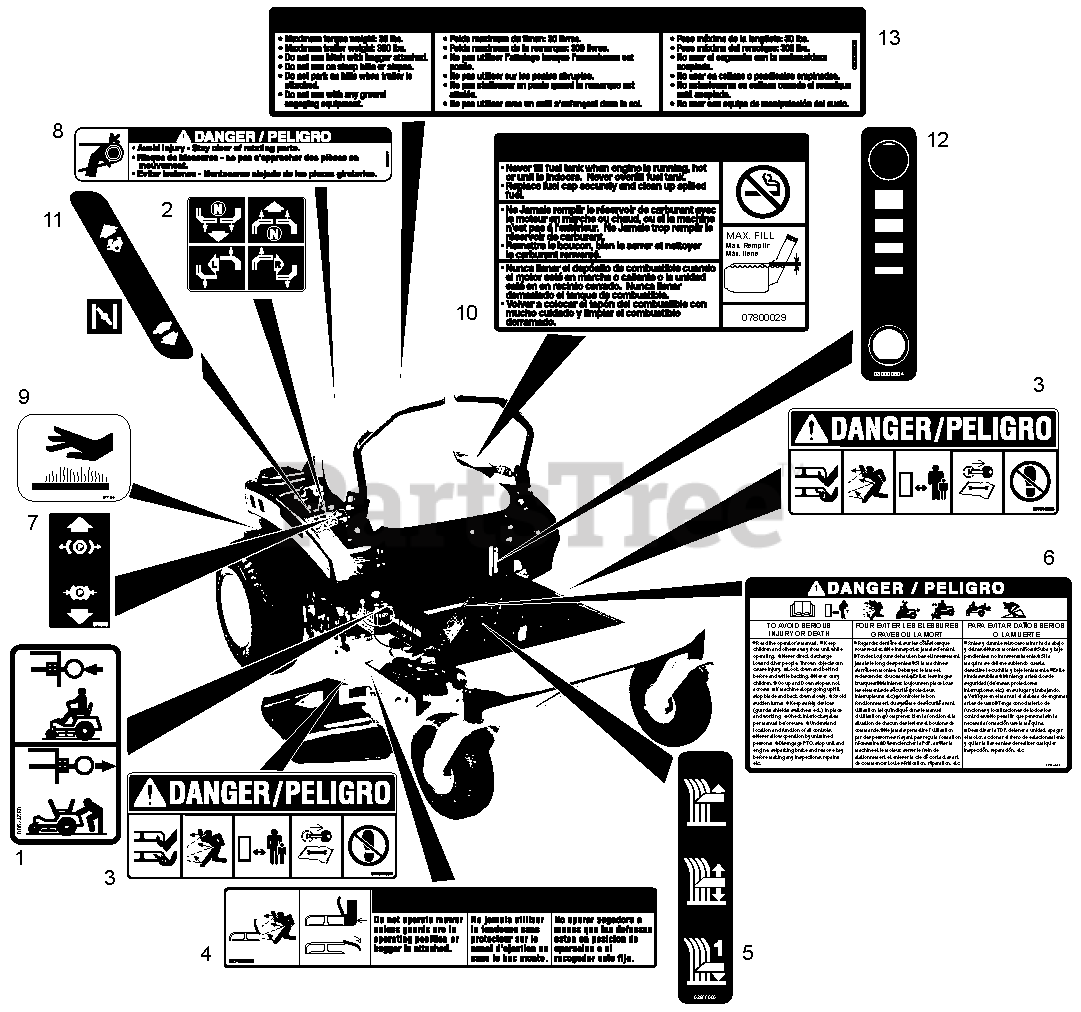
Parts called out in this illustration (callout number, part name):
1	Decal, Transmission Disconnect
2	Decal, Instructional Steering
3	Decal, Mower Pan Head Danger
4	Decal, Warning
5	Decal, Cut Height
6	Decal, Bilingual Danger
7	Decal, Parking Brake Lever
8	Decal, Danger
9	Decal, Hot Surface
10	Decal, Fuel Warning
11	Decal, Throttle Control
12	Decal, Fuel Level
13	Decal, Trailer Hitch (915148, 150, 170)
